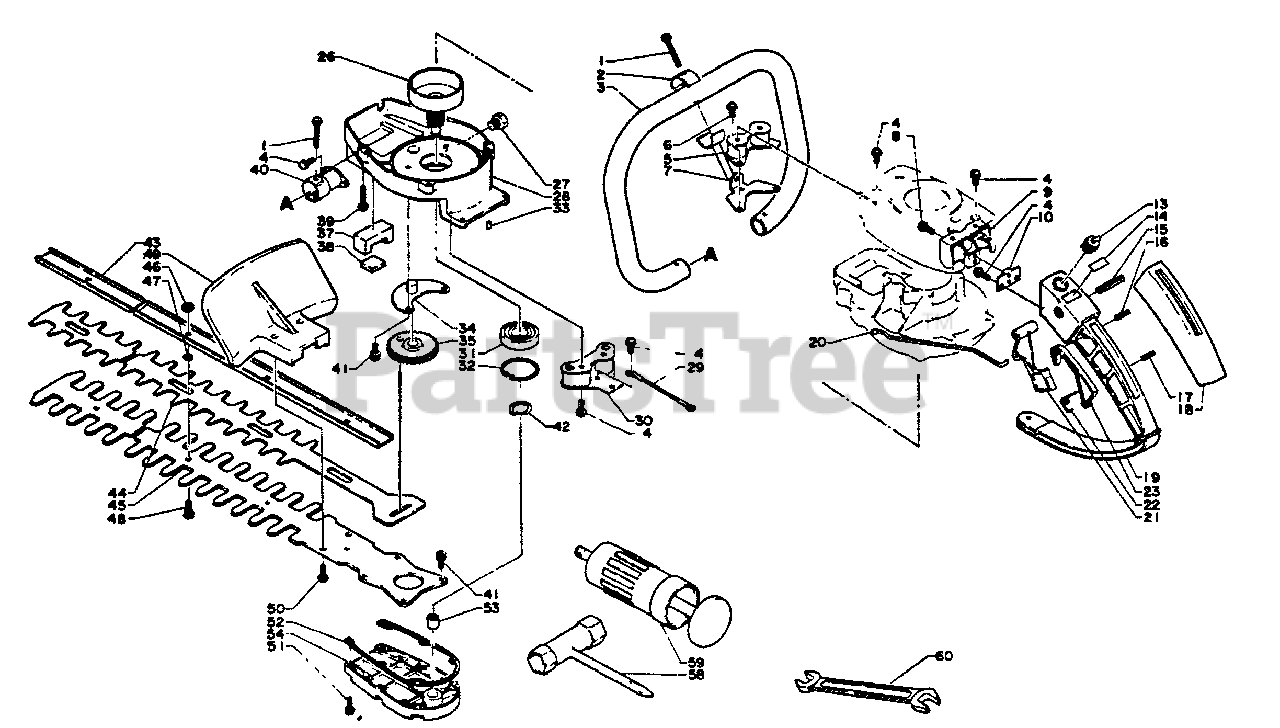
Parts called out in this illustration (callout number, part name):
1	SCREW - 4X30
3	HANDLE - FRONT
4	SCREW - 4X12
6	SCREW - 4X8
7	BRACKET, HANDLE
8	SCREW - 4X12
10	PLATE
13	IGNITION SWITCH ASSY
14	LABEL - STOP
15	PIN - SPRING -- 5X32
16	PIN - SPRING -- 4X16
17	PIN - SPRING -- 3X14
19	HANDLE
20	ROD, THROTTLE
21	TRIGGER, THROTTLE
23	LOCKOUT, THROTTLE
26	DRUM, CLUTCH
27	BOLT - 8X8
28	CASE, GEAR
29	LEAD - GROUND
30	CUSHION
31	BEARING, BALL - 6003
32	RING, RETAINING - 35
33	PIN - LOCATING
34	SHAFT GEAR ASSY
35	GEAR - SPUR
37	SEAL, FELT
38	SEAL, FELT
39	SCREW - 4X22
41	SCREW - 4X14
42	RING, RETAINING - 16
43	SUPPORT, BLADE
44	BLADE - UPPER
45	BLADE - LOWER
46	LOCKNUT - 5
47	SPACER
48	SCREW - 5X12
49	GUARD
50	SCREW - 5X12
51	SCREW - 4X14
52	GASKET, GEAR CASE
53	BEARING, NEEDLE
54	LID, GEAR CASE
58	T-WRENCH
59	PUMP, GREASE
60	SPANNER - 10X13mm
